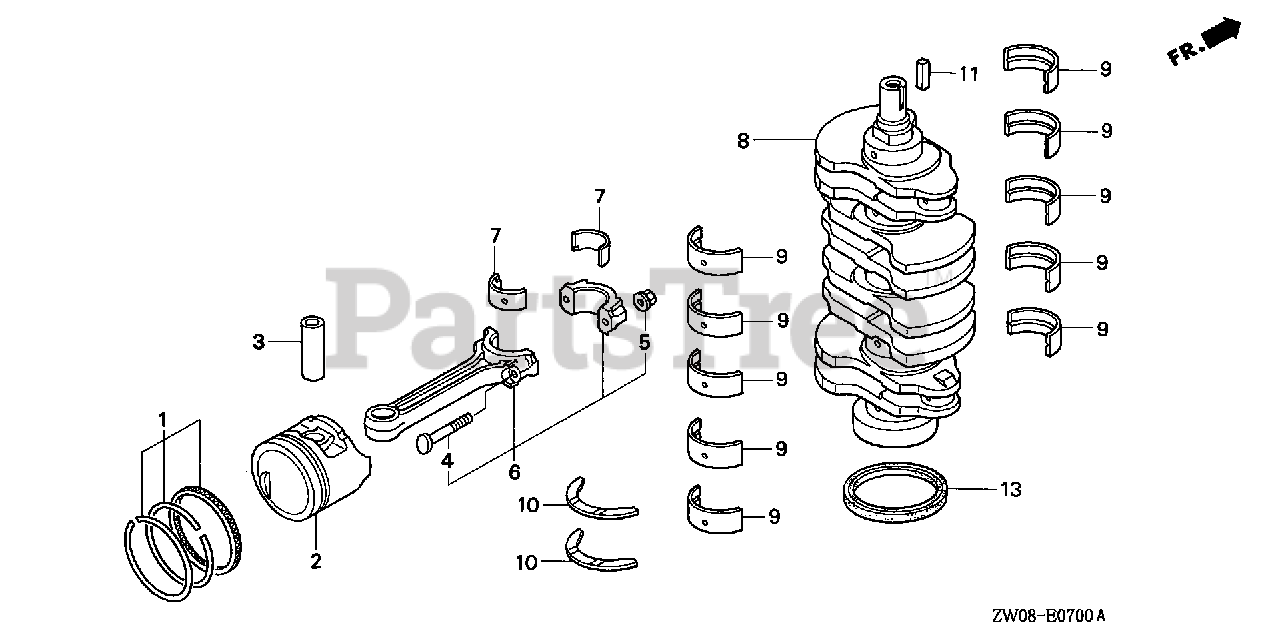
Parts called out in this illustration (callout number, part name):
1	RING SET, PISTON (STD)
1	RING SET, PISTON (OS 0.25)
2	PISTON (STD)
2	PISTON (OS 0.25)
3	PIN, PISTON
4	BOLT, CONNECTING ROD
5	NUT, CONNECTING ROD
6	ROD, CONNECTING
7	BEARING A, CONNECTING ROD (BLUE) (GLACIER DAIDO)
7	BEARING B, CONNECTING ROD (BLACK) (GLACIER DAIDO)
7	BEARING C, CONNECTING ROD (BROWN) (DAIDO)
7	BEARING C, CONNECTING ROD (BROWN) (GLACIER DAIDO)
7	BEARING D, CONNECTING ROD (GREEN) (DAIDO)
7	BEARING D, CONNECTING ROD (GREEN) (GLACIER DAIDO)
7	BEARING E, CONNECTING ROD (YELLOW) (DAIDO)
7	BEARING E, CONNECTING ROD (YELLOW) (GLACIER DAIDO)
7	BEARING F, CONNECTING ROD (PINK) (DAIDO)
7	BEARING F, CONNECTING ROD (PINK) (GLACIER DAIDO)
7	BEARING G, CONN ROD
7	BEARING G, CONNECTING ROD (RED) (GLACIER DAIDO)
8	CRANKSHAFT
9	BEARING A, MAIN (BLUE) (TAIHO)
9	BEARING B, MAIN (BLACK) (TAIHO)
9	BEARING C, MAIN (BROWN) (TAIHO)
9	BEARING D, MAIN (GREEN) (TAIHO)
9	BEARING E, MAIN (YELLOW) (TAIHO)
9	BEARING F, MAIN (PINK) (TAIHO)
9	BEARING G, MAIN (RED) (TAIHO)
10	WASHER, THRUST (TAIHO)
11	KEY, PARALLEL (4.5X18)
13	OIL SEAL (98X80X10) (NOK)
